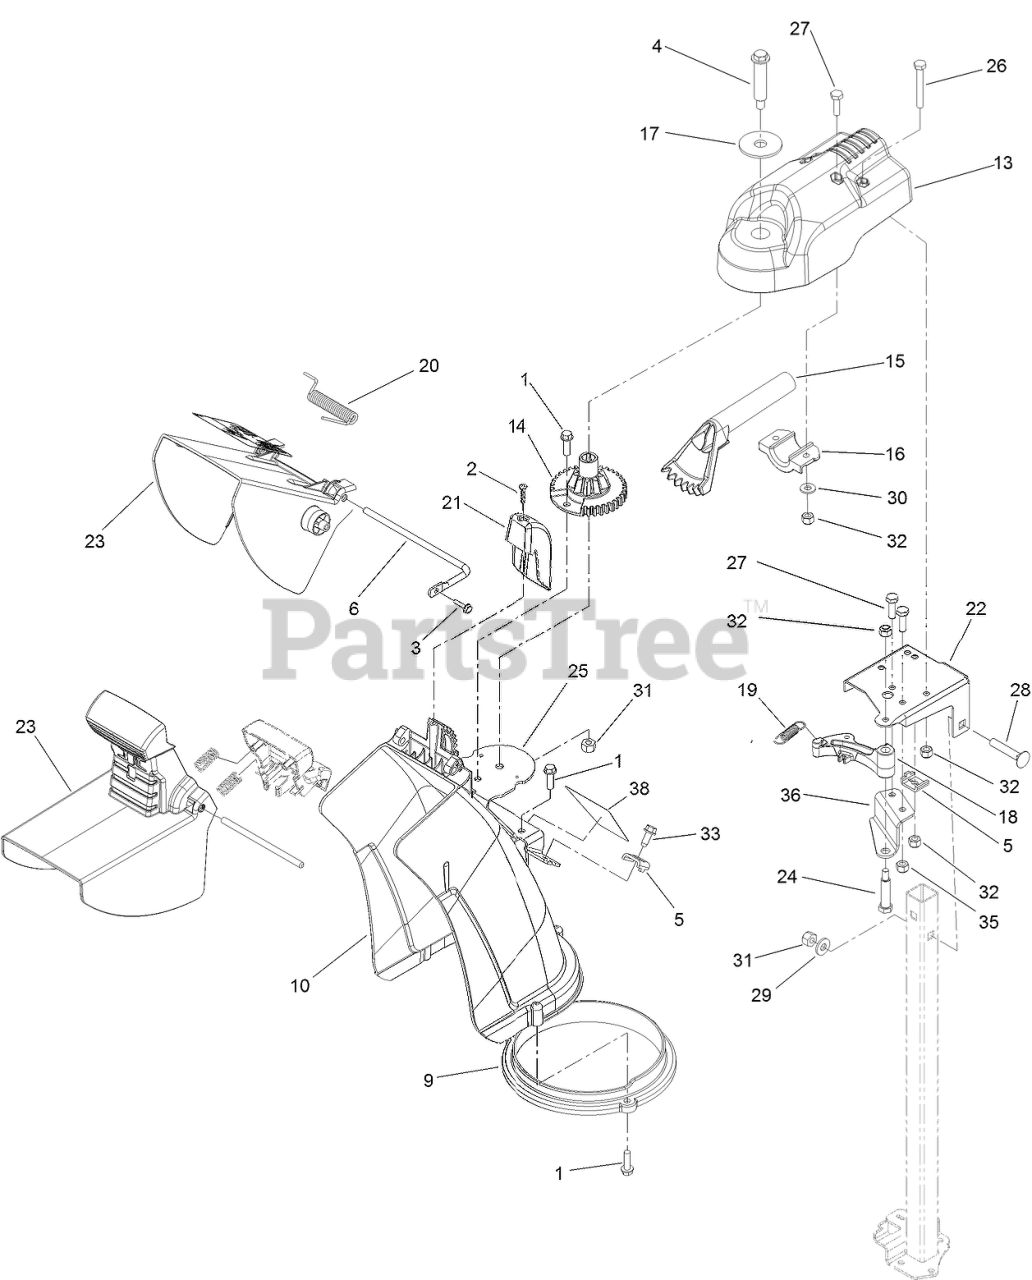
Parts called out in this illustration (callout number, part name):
1	SCREW-HWH
2	SCREW-PPH
3	SCREW-HWH
4	BOLT-SHOULDER
5	CLAMP-CABLE
6	ROD-DEFLECTOR
9	RING-CHUTE
10	CHUTE-DISCHARGE
13	MOUNT-CHUTE, DISCHARGE
14	GEAR-CHUTE
15	GEAR-BEVEL
16	MOUNT-GEAR, BEVEL
17	WASHER-FLAT
18	LATCH-CHUTE
19	SPRING-LATCH, CHUTE
20	SPRING-TORSION
21	CHUTE-COVER
22	BRACKET-SUPPORT, CHUTE
23	DEFLECTOR-CHUTE
24	BOLT-SHOULDER
25	BRACKET-MOUNT, CHUTE
26	SCREW-HH
27	SCREW-HH
28	SCREW-CARR
29	WASHER-FLAT
30	WASHER-FLAT
31	NUT-LOCK, NI
32	NUT-LOCK, NI
33	SCREW-HWH
35	NUT-LOCK, NI
36	BRACKET-SUPPORT, LATCH
38	DECAL-GUARANTEE
